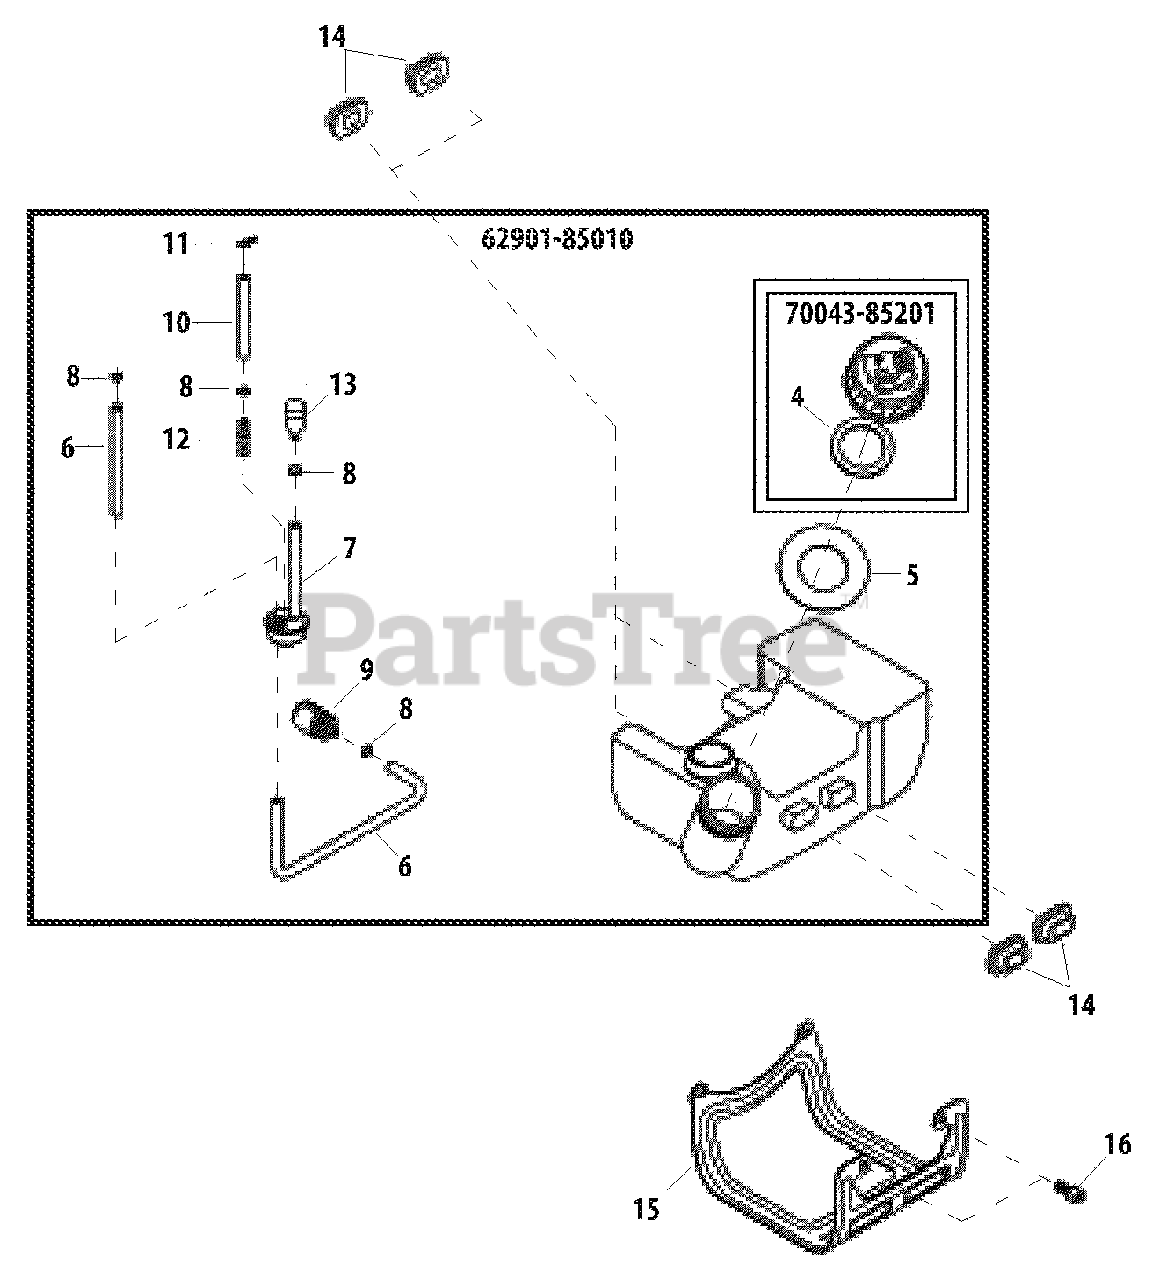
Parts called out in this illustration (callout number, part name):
4	GASKET, CAP
5	PLATE, CAUTION
6	PIPE - FUEL
7	GROMMET
8	RING, RETAINING - 6
9	FILTER, FUEL
10	PIPE - RETURN
11	CLIP - SPRING
12	CONNECTOR, PIPE
13	ELEMENT, BREATHER
14	CUSHION, FUEL TANK
15	GUARD, FUEL TANK
16	SCREW - 5X8
62901-85010	FUEL TANK ASSY
70043-85201	CAP ASSY
